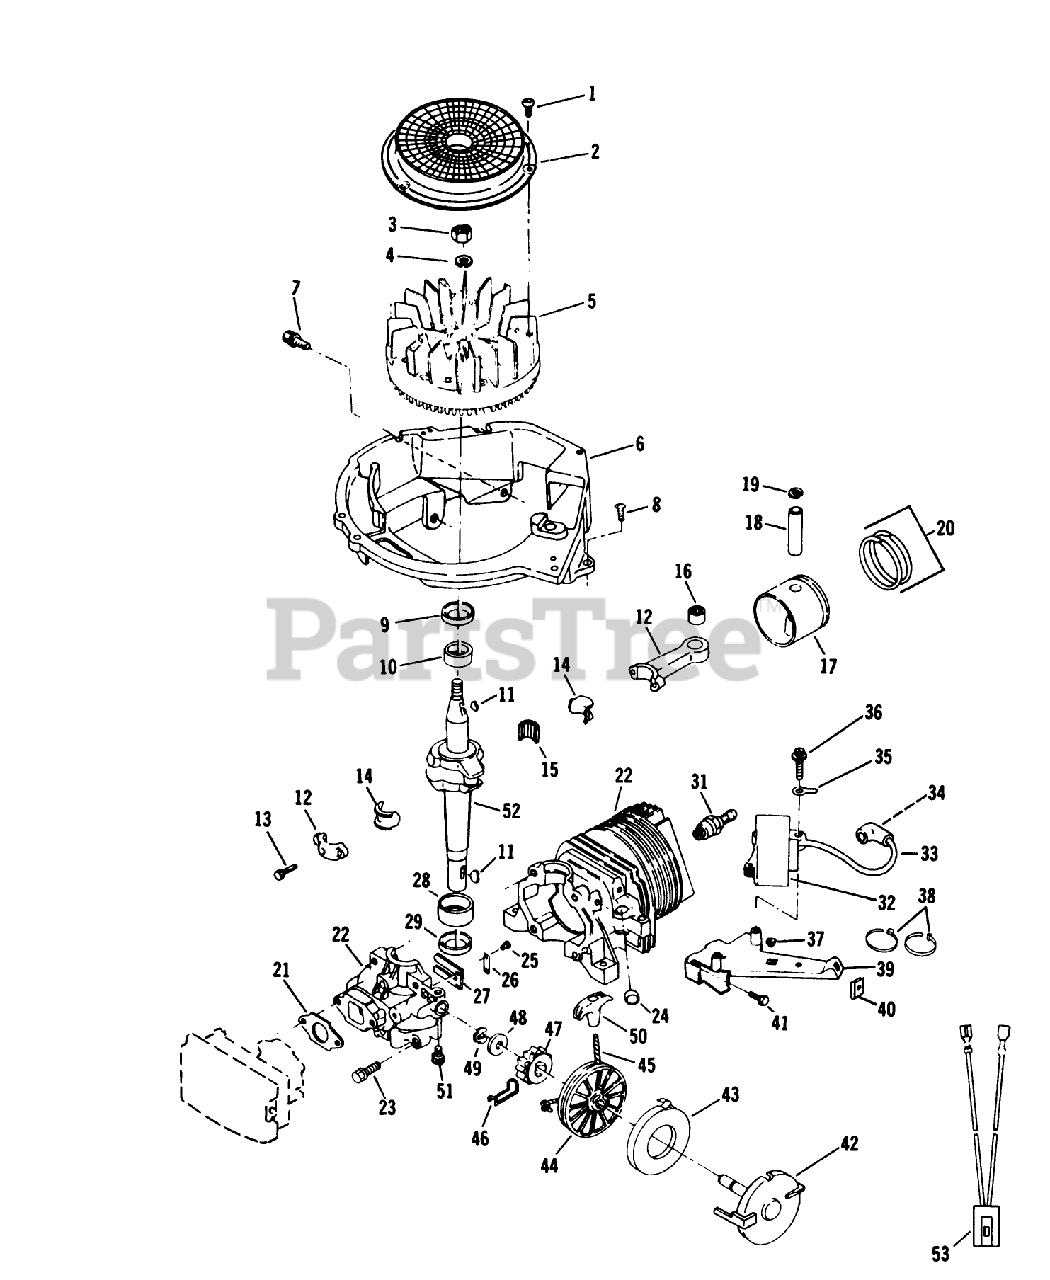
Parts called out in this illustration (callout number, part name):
1	SCREW F
3	NUT
7	SCREW-SEMS
8	SCREW F
10	BEARING V
11	KEY
13	SCREW-HSH
14	LINER ASM
16	BEARING AY F
19	RING-RETAINING
21	GASKET CARB S
23	SCREW S
24	PLUG-CORE VF
26	PLATE-BACKUP, REED
28	BEARING V
29	SEAL-OIL
33	HT LEAD&COVER XEV
35	TERMINAL S
37	NUT-CLIP
40	NUT-SPEED
42	SPRING CUP&PIN S
43	SPRING&RET.AY S
44	PULLEY STARTER S
48	WASHER S
50	HANDLE STARTER S
